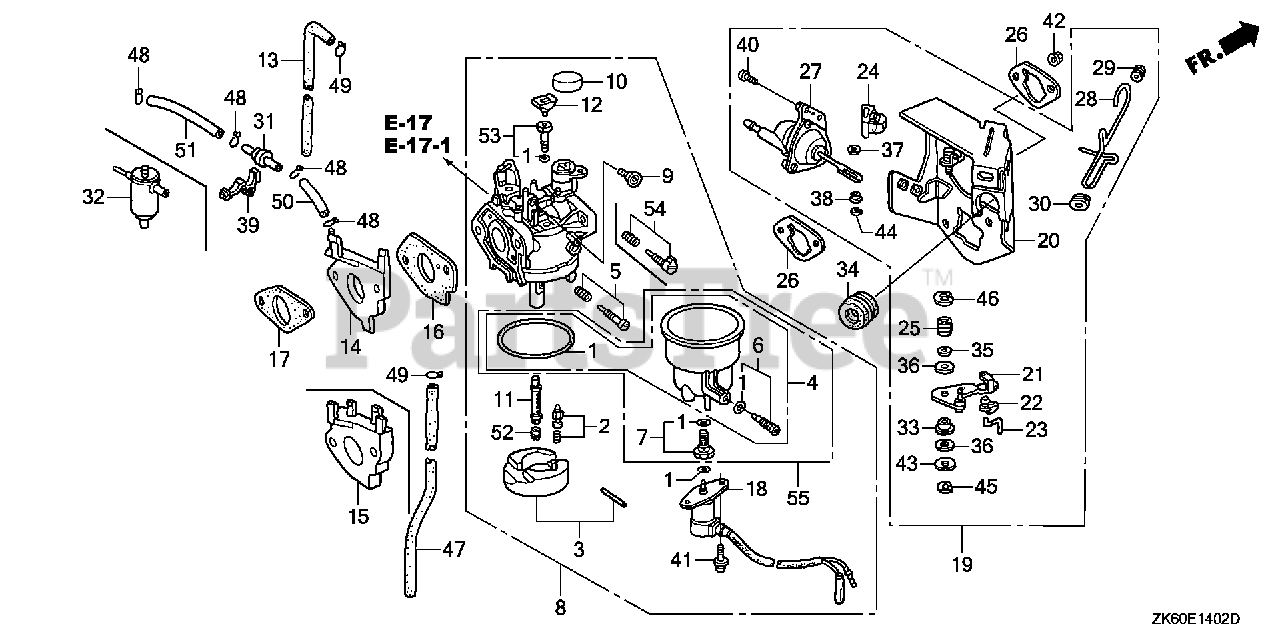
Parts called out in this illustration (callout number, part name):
1	GASKET SET (CARBURETOR NO.)
2	VALVE SET, FLOAT
4	CHAMBER SET, FLOAT
6	SCREW SET, DRAIN (CARBURETOR NO.)
8	CARBURETOR ASSY. (BE87A B/C)
8	CARBURETOR ASSY. (BE87A C)
9	SCREW, THROTTLE STOP
10	CAP, CHOKE DUST
11	NOZZLE, MAIN
12	COLLAR, SETTING
14	INSULATOR, CARBURETOR
16	GASKET, CARBURETOR
17	GASKET, INSULATOR
18	VALVE ASSY., SOLENOID
19	STAY ASSY., MANUAL CHOKE
20	STAY, SOLENOID
21	LEVER, CHOKE
22	JOINT, ROD
23	ROD, CHOKE
24	STOPPER, CHOKE ROD
25	SPRING, MANUAL CHOKE
26	GASKET, AIR CLEANER
27	DIAPHRAGM ASSY.
28	ROD, CHOKE CONTROL
29	GROMMET, CHOKE ROD
30	GUIDE, CHOKE ROD
31	VALVE, DASHPOT CHECK
32	VALVE ASSY., SOLENOID
33	BUSH, ARM PIVOT
34	GROMMET, FENDER
35	WASHER, CHOKE LEVER
36	SEAL, CHOKE LEVER
37	WASHER, THRUST (2.7X8)
38	COLLAR, LEVER
39	CLIP, WIRE HARNESS
40	SCREW, PAN (5X12)
41	SCREW-WASHER (5X12)
42	NUT, FLANGE (6MM)
43	WASHER, PLAIN (5MM)
44	E-RING (2MM)
45	E-RING (4MM)
46	E-RING (7MM)
48	CLIP, TUBE (B7)
50	BULK HOSE, VACUUM (3.5X8000) (3.5X75)
51	BULK HOSE, VACUUM (3.5X8000) (3.5X130)
52	JET, MAIN (#98) (CARBURETOR NO.)
52	JET, MAIN (#100) (CARBURETOR NO.)
52	JET, MAIN (#102) (CARBURETOR NO.)
53	JET SET, PILOT (#45)
54	SCREW SET (CARBURETOR NO.)
